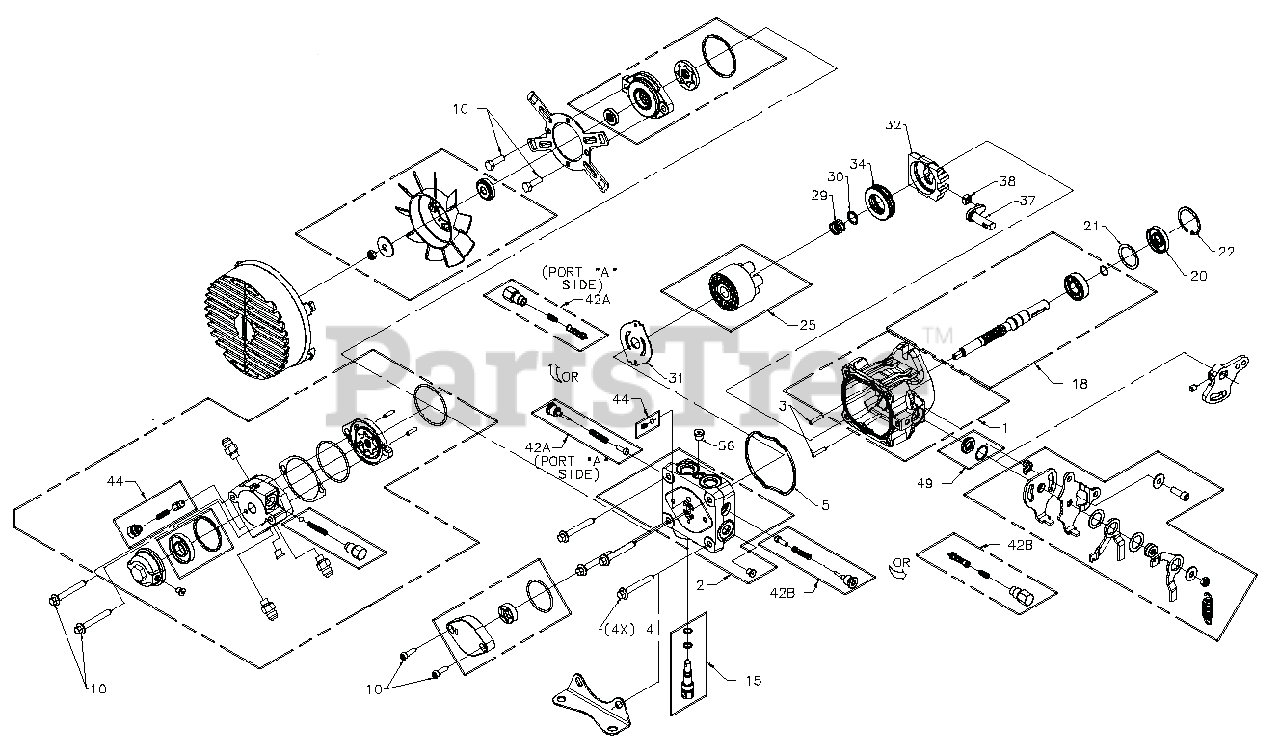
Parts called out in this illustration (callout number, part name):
1	KIT, HSG
2	KIT, END CAP W/PPT & STD
3	PIN, .219X1
4	HFHCS M8X60
5	KIT, CHG PUMP
10	SCREW, CAP M6X1X25
15	KIT, BYPASS VALVE
18	KIT, PUMP SHAFT 15MM KEYW
20	SEAL, LIP 17X40X7
21	WASHER 1.23X1.56X.04
22	RING, RET 1.56 INT
25	KIT, 10 CC BLOCK
29	SPRING. BLOCK
30	WASHER. THRUST .59 X .79 X .04
31	PLATE, VALVE
32	SWASHPLATE. VARIABLE
34	BEARING. THRUST 30 X 52 X 13
37	ARM, TRUNNION 10 CC
38	GUIDE. SLOT
42	KIT, SHOCK VALVE 200 BAR
44	KIT, CHG RELIEF
49	KIT, PUMP SEAL
56	PLUG 7/16-20 (METAL)
NS	KIT, PUMP SEAL
